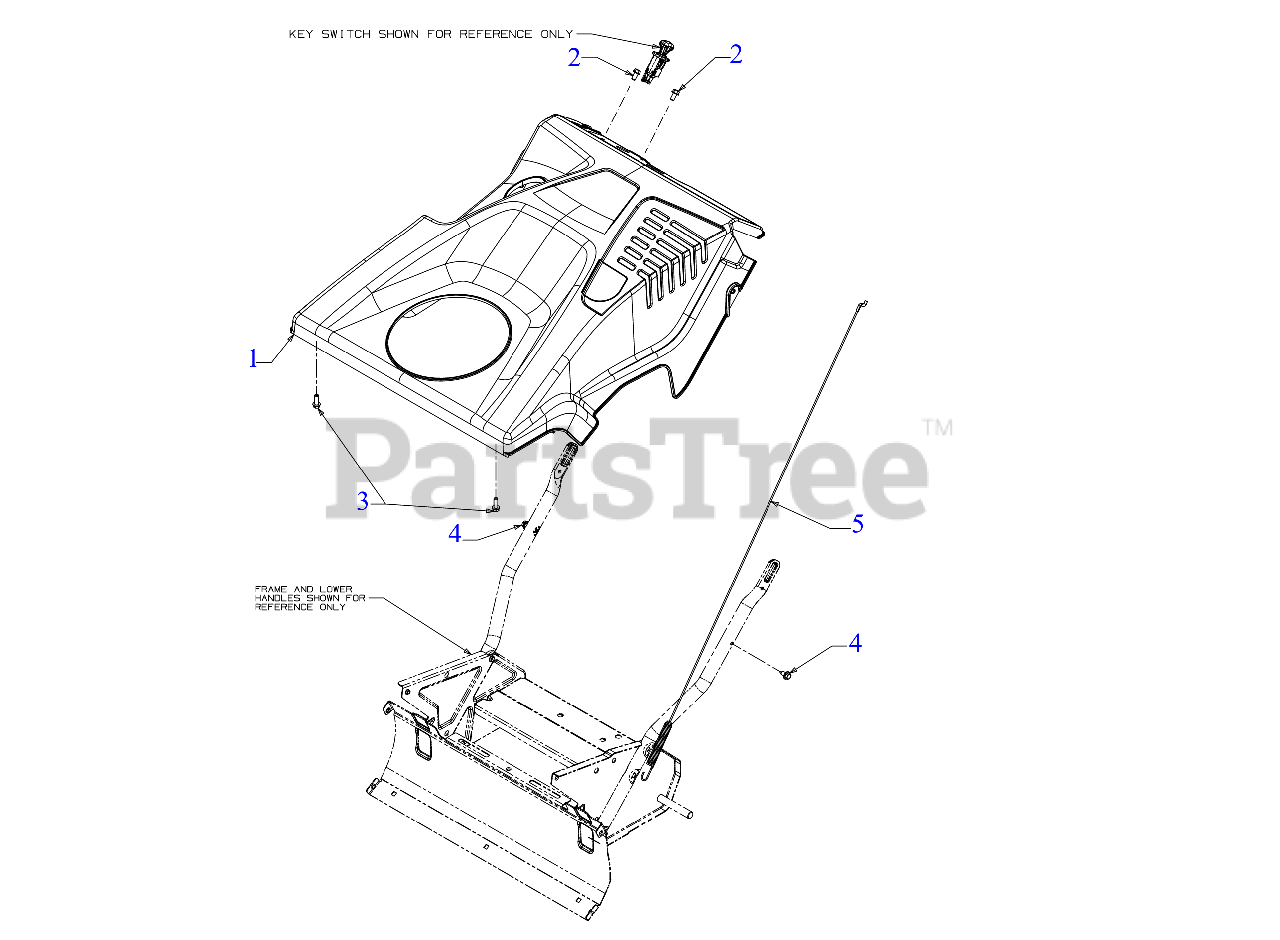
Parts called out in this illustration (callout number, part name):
1	COVER ASSEMBLY E-STYLE (YELLOW)
2	HEX SCREW 1/4-15 x .50
3	SCREW 1/4-15 x .750
4	SCREW 1/4-20X.625
5	CLUTCH CABLE 35.03"
